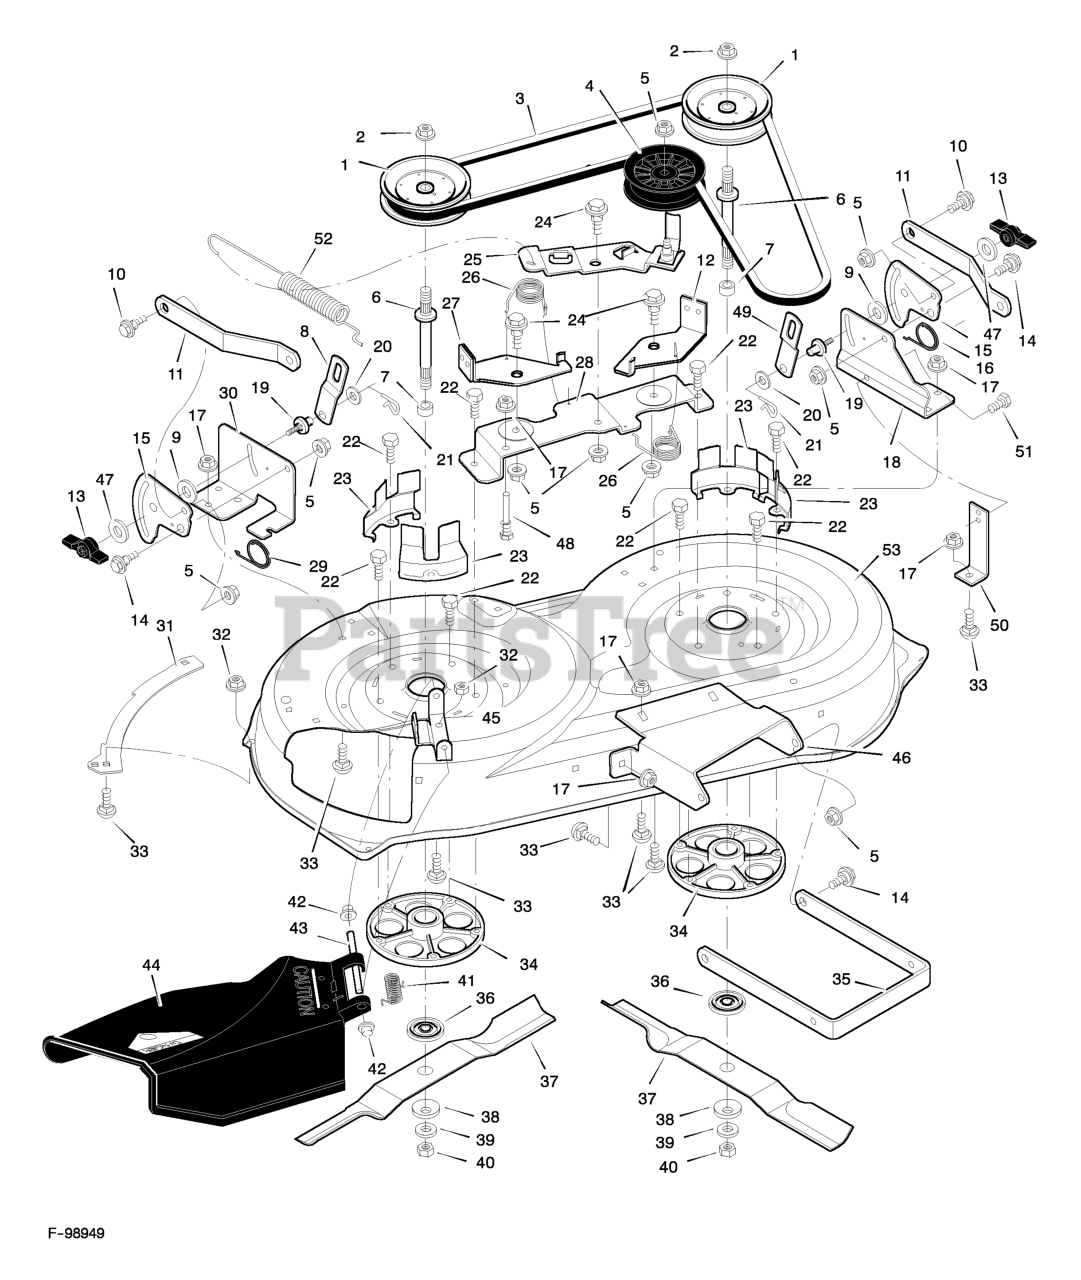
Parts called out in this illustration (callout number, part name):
1	Pulley, Jackshaft
2	Nut, Hex
3	Belt, Mower Drive
4	Pulley, Idler
5	Nut, Flange
6	Jackshaft
8	Link, Right Lift
9	Pad, Friction
10	Bolt, Shoulder
11	Bracket, Suspension
12	Pad Assembly, Left Brake
13	Knob
14	Bolt, Shoulder
15	Plate, Suspension
17	Nut, Flange
18	Bracket, Suspension
19	Pin, Hanger
21	Pin, Cotter
22	Bolt
23	Cover, Pulley
24	Bolt, Shoulder
25	Arm, Idler
27	Pad Assembly, Right Brake
28	Bracket Assembly, Brake
30	Bracket, Suspension
31	Plate
32	Nut, Flange
33	Bolt, Carriage
34	Housing, Jackshaft
35	Bracket, Suspension
36	Adapter, Blade
42	Cap, Push On
43	ROD, Deflector
44	Deflector
45	Bracket, Deflector
46	Bracket, Front Hanger
48	Guide, Belt
49	Link, Left Lift
50	Bracket, Support
52	Spring, Extension
53	Housing, Blade
